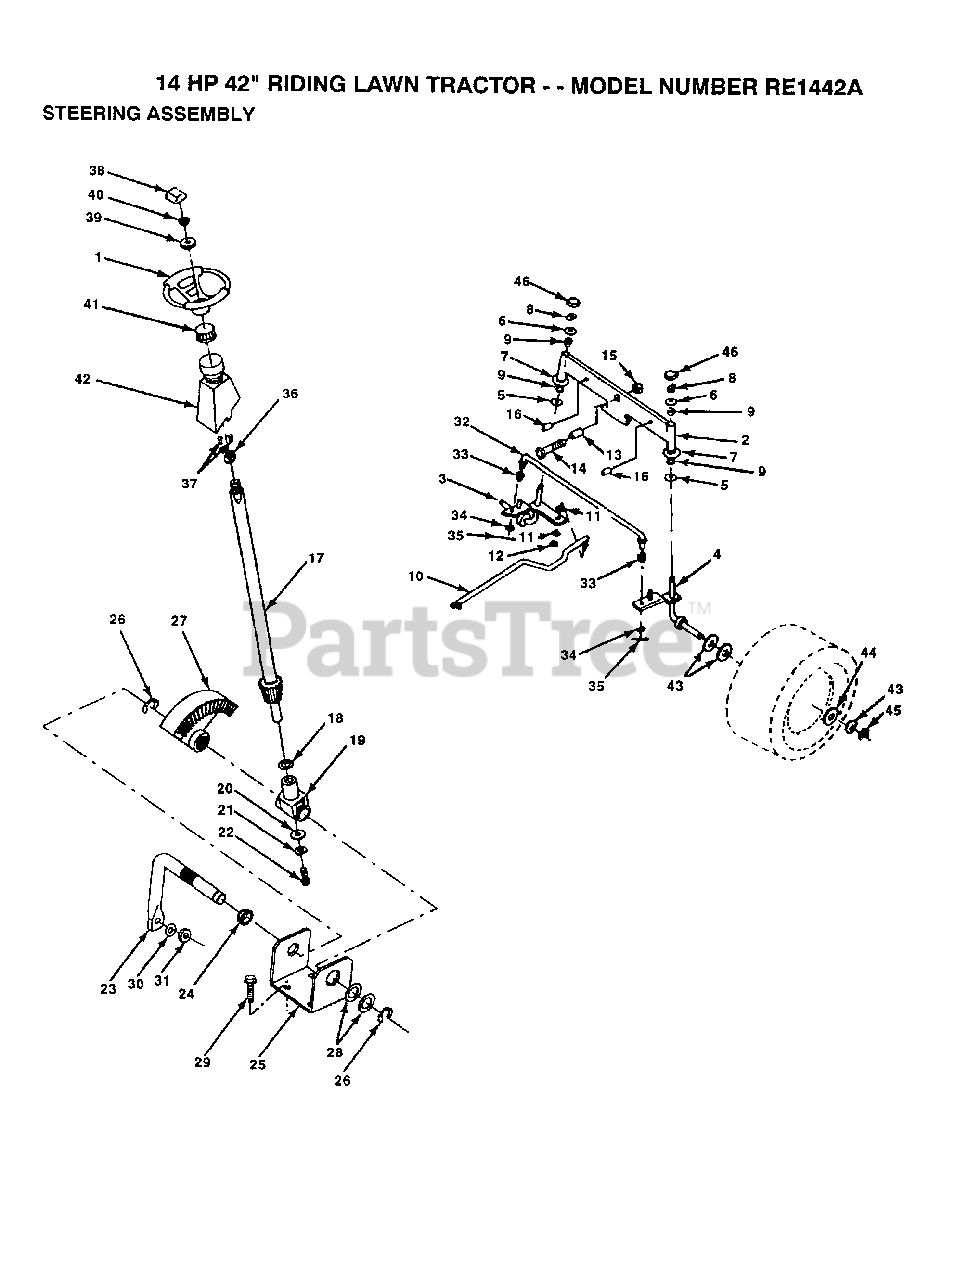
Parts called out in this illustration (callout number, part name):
3	SPINDLE LH
4	SPINDLE RH
5	WASHER .T
6	WASHER
7	WASHER
8	RING
9	COL. SRTG. BEAR.
11	LOCKWASHER
13	BEARING
14	BOLT HEX 5/8-11
16	AXLE PIN
17	SHAFT ASM
18	THRUST WASHER
19	SUPPORT.SHAFT
21	LOCKWASHER
22	"SCREW,SPECIAL"
24	NYLINER T
25	"BRKT,STEERING"
26	RING
28	WASHER .T
29	SCREW
30	LOCKWASHER
32	TIE ROD
33	BUSHING.DRAGLINK
34	WASHER
35	COTTER PIN
38	ST WHL INSERT CAP
39	WASHER T
40	GRIPCO NUT
41	ADAPTER-WHEEL LT
42	"TUBE, STR SHAFT"
43	WASHER
44	WASHER
45	RING
46	CAP
